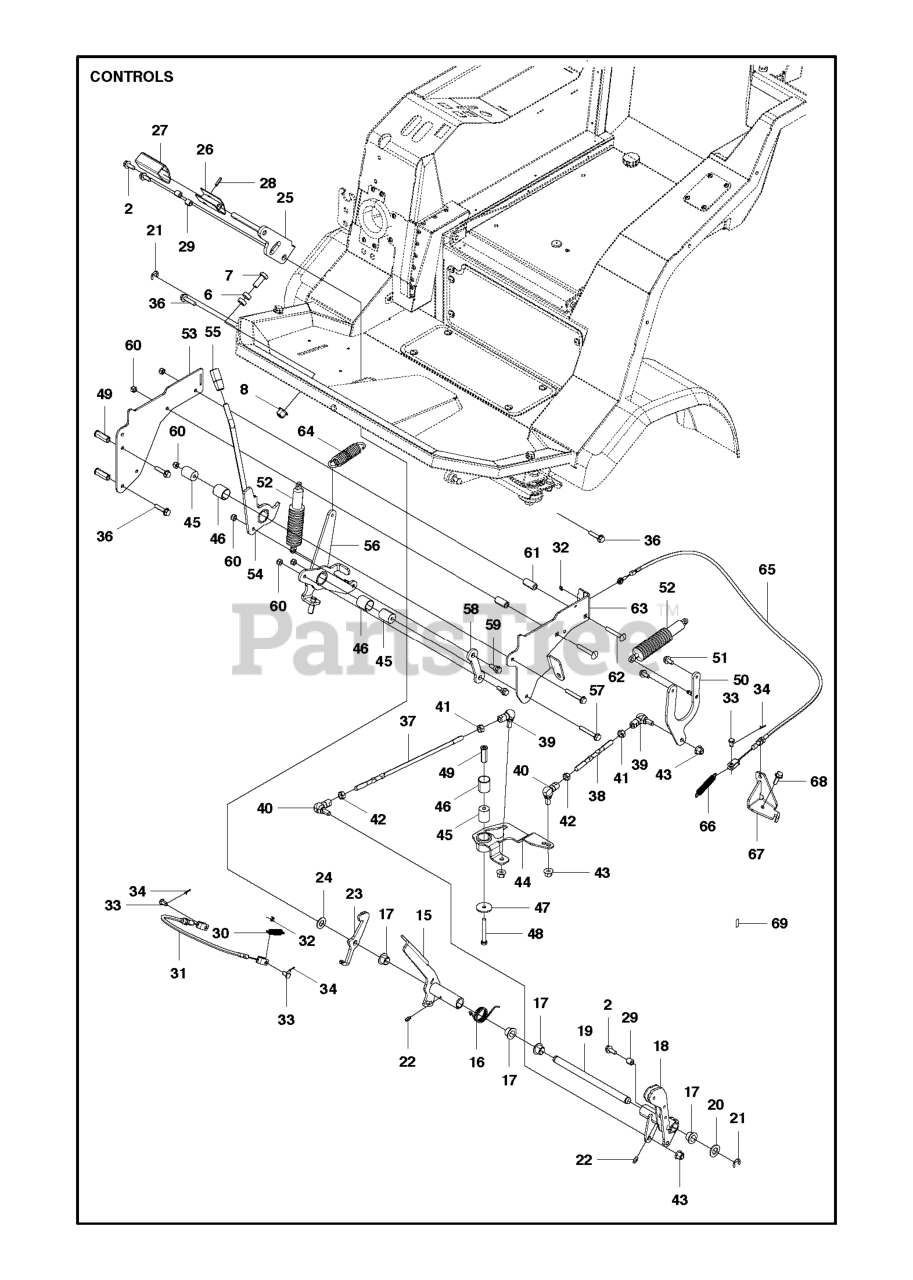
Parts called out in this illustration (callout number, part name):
17	BUSHING
22	GREASE NIPPLE
24	WASHER - M12
27	PEDAL RUBBER
33	Clevis Pin
34	Cotter Pin
36	SCREW EHHFM
46	BUSHING
52	SHOCK ABSORBER
57	SCREW EHHFM
60	LOCKNUT M8
68	BOLT
